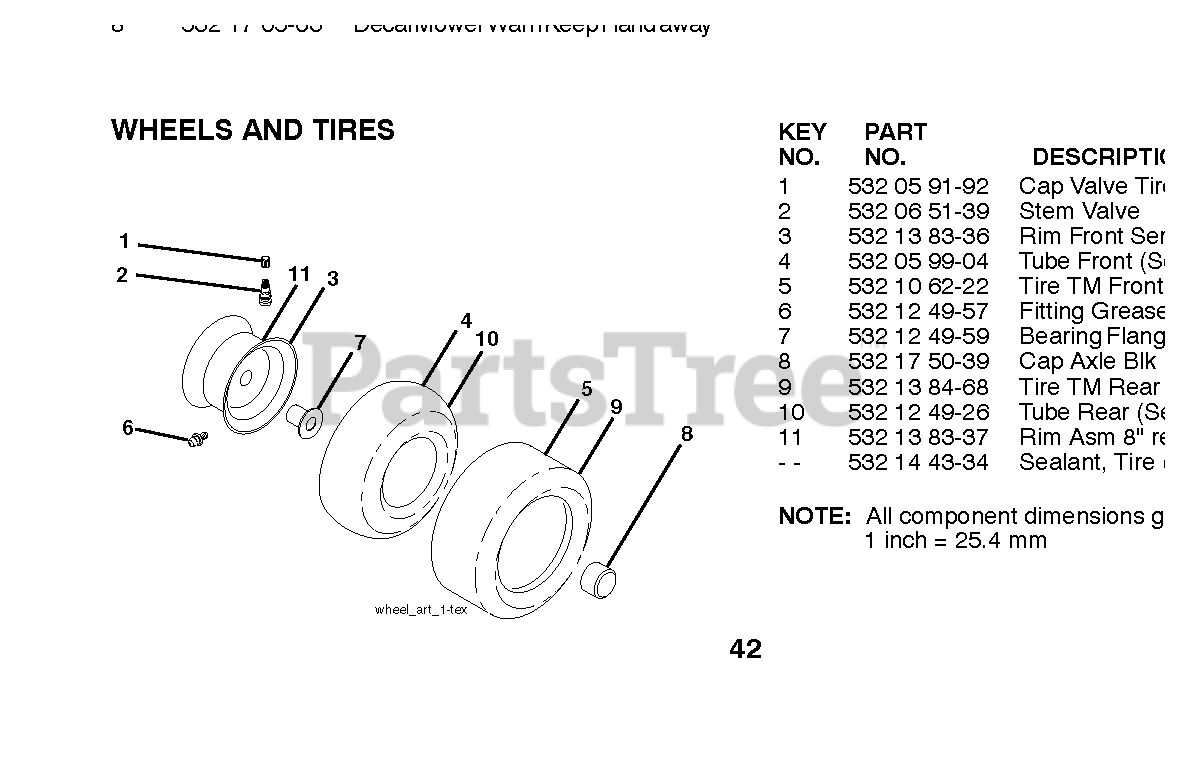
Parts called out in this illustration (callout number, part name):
2	VALVE STEM LT
3	RIM ASM 6" FRONT SILVER
4	TUBE.5.3/4.5/6
5	TIRE HEAVY DUTY
6	FITTING LT
7	BEARING T
8	CAP, AXLE BLK
9	TIRE.20X8-8.TURF.SAVER
10	TUBE
11	RIM ASM 8" REAR SILVER
